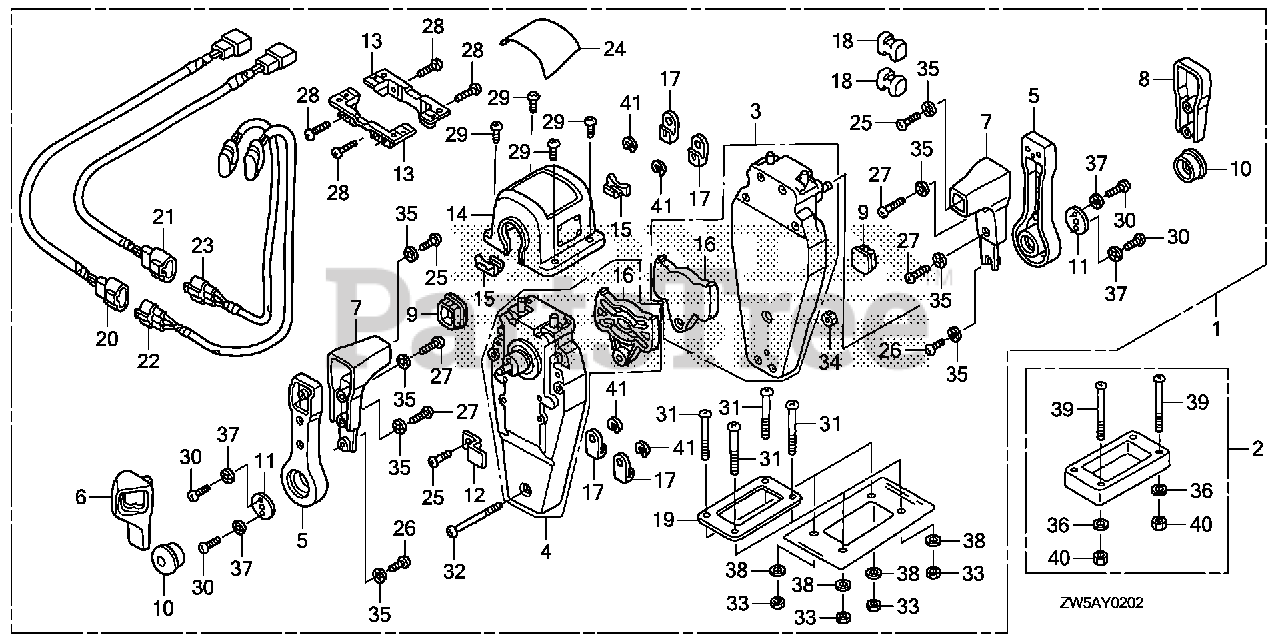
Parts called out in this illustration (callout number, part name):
1	BOX KIT, REMOTE CONTROL (TOP MOUNT DUAL)(R)
2	SPACER KIT, REMOTE CONTROL BOX (TOP MOUNT DUAL)
3	HOUSING ASSY., L. (INNER) (TOP MOUNT)
4	HOUSING ASSY., R. (INNER) (TOP MOUNT)
5	HANDLE, REMOTE CONTROL
6	COVER, L. GRIP
7	GRIP, REMOTE CONTROL HANDLE
8	COVER, DUAL GRIP
9	CAP, GRIP
10	BUTTON, THROTTLE
11	PLATE, HANDLE
12	PLATE, CABLE CLAMP
13	BRACKET, REMOTE CONTROL HOUSING
14	HOUSING, DUAL REMOTE CONTROL BOX
15	HOUSING, LEAD
16	PLATE, DWELL
17	TERMINAL, CABLE
18	SPACER, CABLE CLAMP
19	GASKET, DUAL
20	SUB-HARNESS ASSY., POWER TRIM-TILT (A)
21	SUB-HARNESS ASSY., POWER TRIM-TILT (B)
22	SWITCH ASSY., POWER TRIM-TILT (A)
23	SWITCH ASSY., POWER TRIM-TILT (B)
24	MARK, REMOTE CONTROL (DUAL)
25	SCREW, PAN (5X16)
26	SCREW, PAN (5X10)
27	SCREW, PAN (5X20)
28	SCREW, PAN (5X18)
29	SCREW, PAN (4X10)
30	SCREW, PAN (6X18)
31	SCREW, PAN (5X40)
32	SCREW, PAN (5X55)
33	NUT, HEX. (5MM)
34	NUT, HEX. (5MM)
35	WASHER, LOCK (5MM)
36	WASHER, PLAIN (5MM)
37	WASHER, LOCK (6MM)
38	WASHER, PLAIN (5MM)
39	SCREW, PAN (5X65)
40	NUT, HEX. (5MM)
41	E-RING (6MM)
